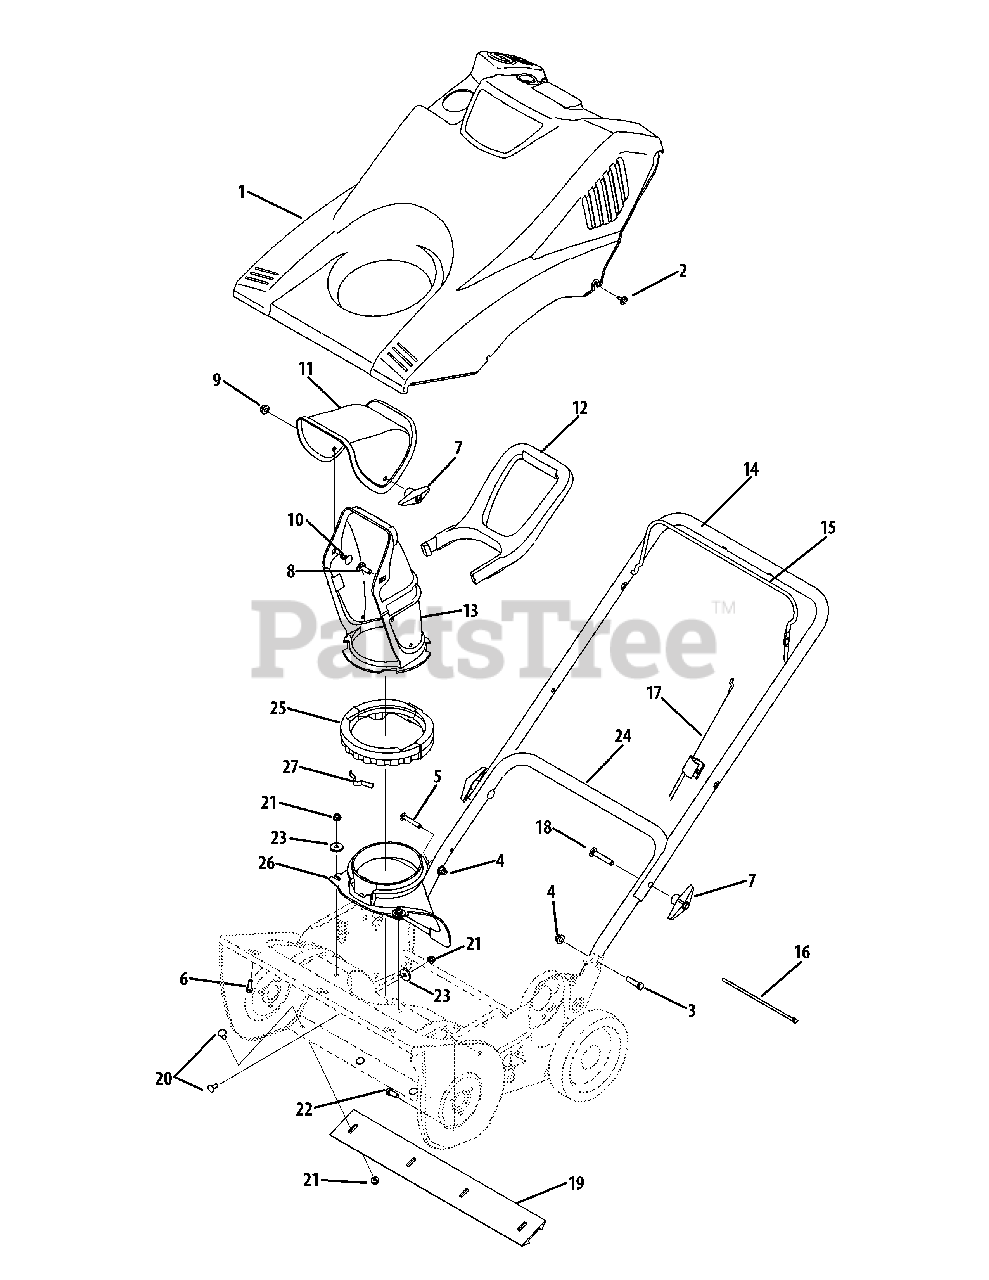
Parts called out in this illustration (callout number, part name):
1	Shroud
2	Hex Screw, 10-16 x .625
3	Hex Flange Screw, 5.16-18 x 1.25
4	Flange Lock Nut, 5.16-18
5	Hex Flange Screw, 5.16-18 x 1.50
6	Hex Screw, 1.4-15 x .750
7	Wing Nut, 5.16-18
8	Carriage Bolt, 5.16-18 x 1.00
9	Flange Lock Nut, 5.16-18
10	Carriage Bolt, 5.16-18 x .750
11	Upper Chute
12	Chute Handle
13	Lower Chute
14	Upper Handle
15	Bail Control
16	Cable Tie, 3.16 x .05 x 7.4
17	Clutch Cable
18	Carriage Bolt, 5.16-18 x 2.00
19	Shave Plate, 21h
20	Carriage Screw, 1.4-20 x .62
21	Flange Lock Nut, 1.4-20
22	Hex Screw, 5.16-18 x .75
23	Flat Washer, .265 x .938 x .120
24	Lower Handle
25	Lower Chute Ring
26	Chute Adapter
27	Chute Adjustment Spring
